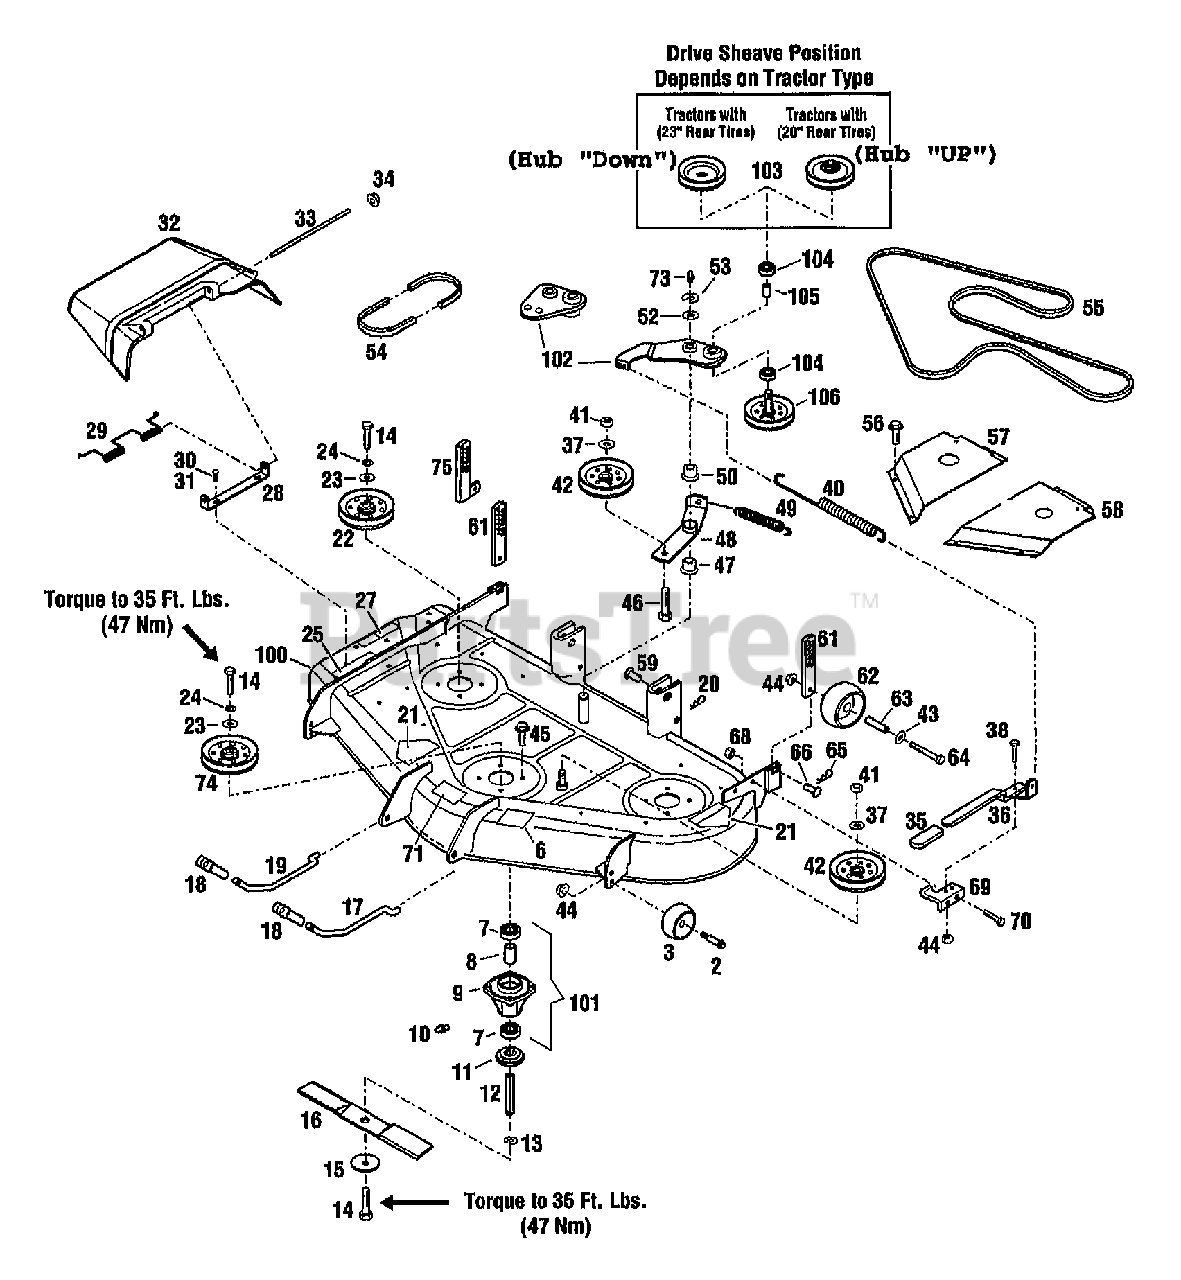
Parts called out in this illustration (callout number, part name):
2	SCR-SHLDR 3/8-16
3	WHEEL-GAGE
6	DECAL-BELT DRIVE
7	BEARING-BALL
9	HOUSING-SPINDLE
10	FITTING-GREASE 1/4-28X2.00
11	SPACER-BLADE
12	SHAFT-SPINDLE
13	RING-RETAINING EXT .694 ID
14	SCR-HH 1/2-14X1.00
15	WASHER-BELLEVILLE
16	BLADE-CUTTER {14051}
16	BLADE-CUTTER {14052}
16	BLADE-LIFT {14051}
16	BLADE-LIFT {14052}
17	ROD-LIFT FRONT LH
19	ROD-LIFT FRONT RH
20	PIN-HITCH .125X2.56 ZP
21	DECAL-OPEI CAUTION
23	WASHER-1.25X.5X.083 ZP
24	WASHER-LK .438 ZP
25	DECAL-CUTTING LINE
27	DECAL-DANGER
29	SPRING-TORSION
30	BOLT-CARR 5/16-18X.63 ZP
31	NUT-TOP/LK 5/16-18 ZP
32	DEFLECTOR-DISCHARGE
34	NUT-PUSH 3/8 ZP
36	ARM-SPRING ENGAGE {14051/052}
36	ARM-SPRING ENGAGEMENT {14051/052}
37	WASHER-FLAT .88X.5X.06 ZP
38	SCR-HH 3/8-16X1.0 G5 ZP
40	SPRING-BELT DRIVE {14051/052}
40	SPRING-EXTENSION 20.75 {14051/052}
41	NUT-TOP LOCK 1/2-13 ZP
42	PULLEY-IDLER
43	WASHER-.986X.437X.083 ZP
44	NUT-LOCK 3/8-16
45	SCR-HFLK 5/16-18X.75
46	BOLT-CARR 1/2-13X1-3/4
47	BUSHING-FLANGE
48	ARM-IDLER
49	SPRING-EXTENSION
50	BEARING-FLANGE
52	SHIM-WASHER
53	RING-RET. EXT .875 ID
55	BELT-V {14051}
55	BELT-V {14052}
56	SCR 1/4-20X.5 FL SELF TAP
57	COVER-BELT RH {14051}
57	COVER-BELT RH {14052}
58	COVER-BELT LH {14051}
58	COVER-BELT LH {14052}
59	PIN-CLEVIS .625X2.25
61	LEVER-GAGE WHEEL ADJUST {14051/052}
61	LEVER-GAGE WHEEL ADJUST {14052}
62	WHEEL-GAGE
63	SPACER-GAGE WHEEL
64	SCR-HH 3/8-16X3.5 G5 ZP
65	CLIP-HAIRPIN .07 DIA
66	PIN-CLEVIS .375 X .937 ZP
68	NUT-HFLK 5/16-18 ZP
69	BRKT-MOUNTING SPRING ARM {14052}
69	BRKT-SPRING ARM MOUNTING {14051/052}
70	SCR-HFLK 5/16-18X.75 ZP
71	DECAL-LIFT ROD
73	FITTING-GREASE 90 DEGREE
74	ASSM-SHEAVE 5"
75	BAR-GAGE WHEEL {14051}
75	BAR-GAGE WHEEL {14052}
100	DECK-MOWER W/DECALS {14051}
100	DECK-MOWER W/DECALS {14052}
100	ASSM-MOWER BASE 42"S/D W/DECAL {14051}
100	ASSM-MOWER BASE 42"S/D W/DECAL {14052}
101	ASSM-MOWER SPINDLE
102	ARM-MOUNTING {14051/052}
102	WELDMENT ASSM-MTG ARM {14051/052}
103	PULLEY-DRIVE
104	BEARING-BALL
105	SPACER-1.04X.875X1.07
106	PULLEY W/SHAFT
